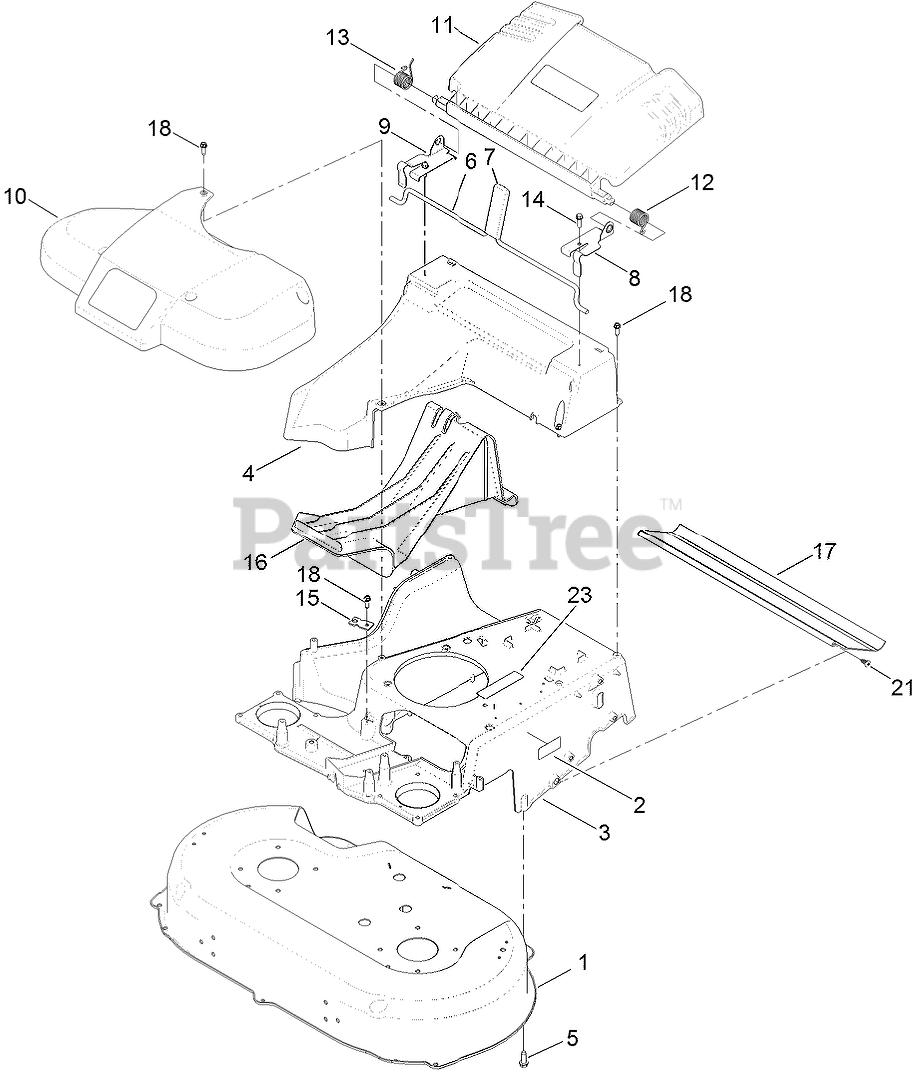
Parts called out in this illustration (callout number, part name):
1	HOUSING ASM
2	DECAL-LOCATION, SERVICE DEALER
4	CHUTE
5	SCREW-HWHTF
6	ROD-RELEASE, HANDLE
7	GRIP-LEVER
8	BRACKET-DOOR, LH
9	BRACKET-DOOR, RH
10	BELT COVER ASM
11	REAR DEFLECTOR ASM
12	SPRING-TORSION
13	SPRING-TORSION
14	SCREW-HWH
15	BRACKET-CABLE, TRACTION
16	PLUG-MULCH
17	SHIELD-TRAILING
18	SCREW-HWHTF
21	SCREW-PTH
23	DECAL-ARRESTER, SPARK
